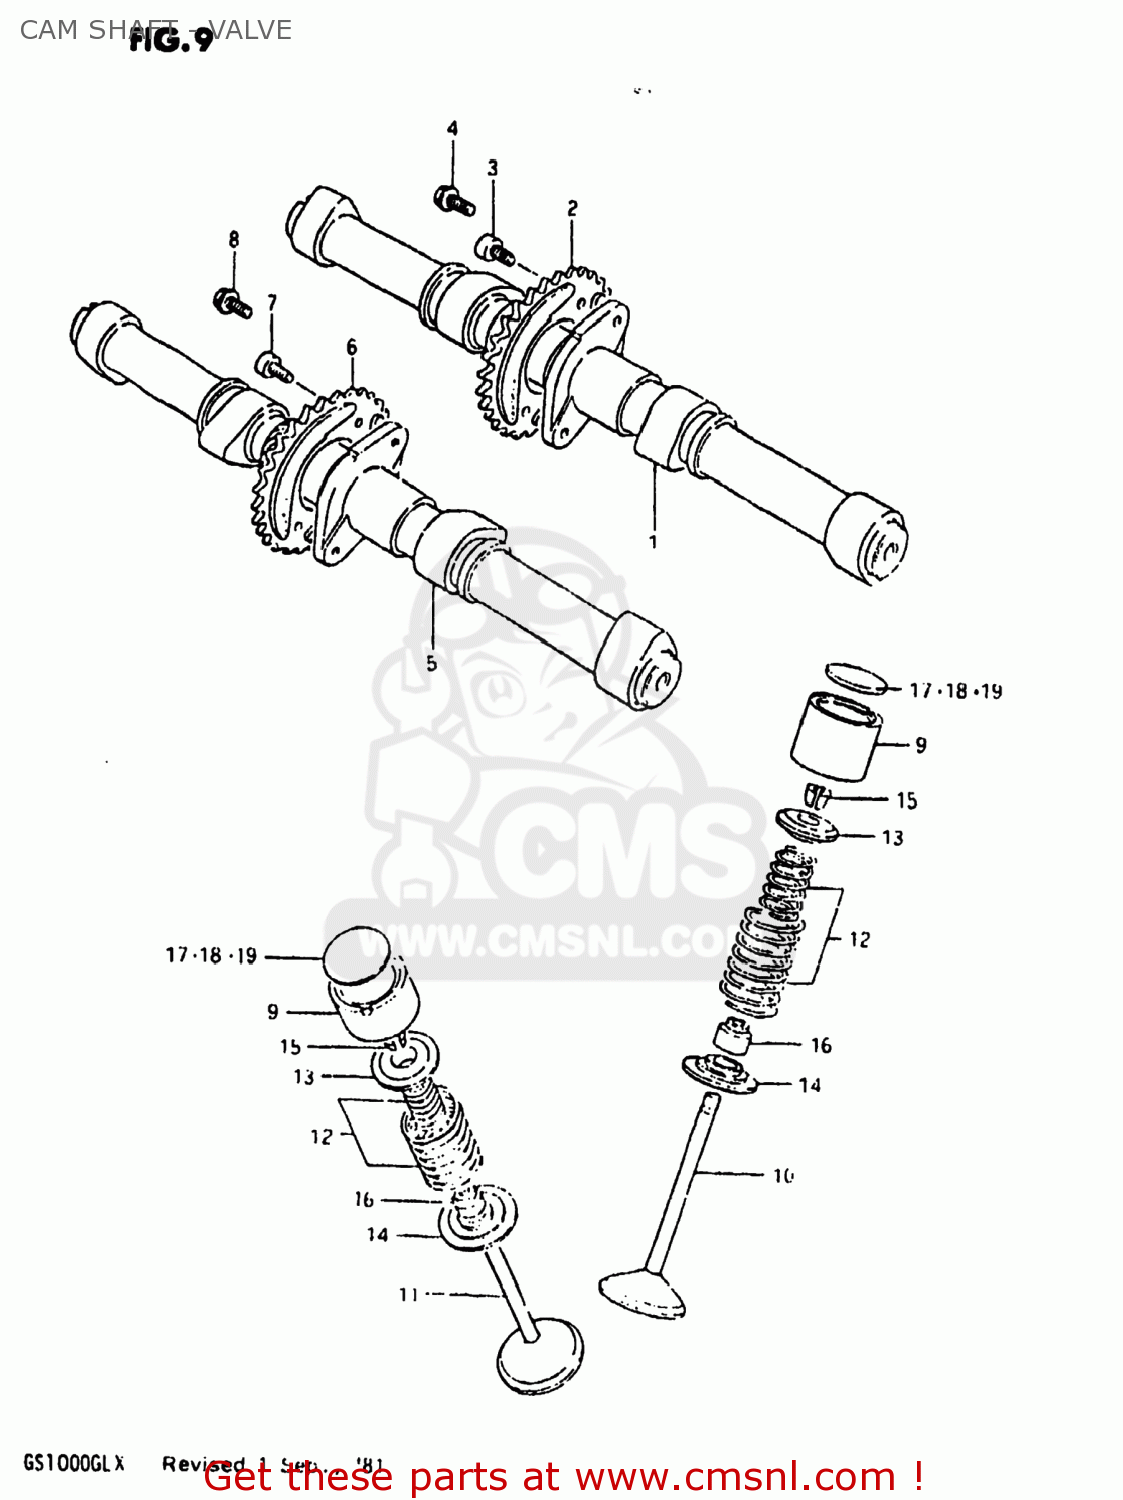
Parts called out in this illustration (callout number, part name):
1	CAMSHAFT
2	SPROCKET,INTAKE CAMSHAFT
3	BOLT 6X11
4	BOLT(7X11)
5	CAMSHAFT,EXHAUST
6	SPROCKET,EXHAUST CAMSHAFT
7	BOLT 6X11
8	BOLT(7X11)
9	TAPPET
10	VALVE,INTAKE
11	VALVE,EXHAUST
12	SPRING SET,VALVE
13	RETAINER,VALVE SPRING
14	SEAT,VALVE SPRING
15	COTTER VALVE
16	SEAL,OIL(7X14.4X9)
17	SHIM,TAPPET
18	SHIM,TAPPET
19	SHIM,TAPPET
20	SHIM SET,TAPPET
21	CASE
